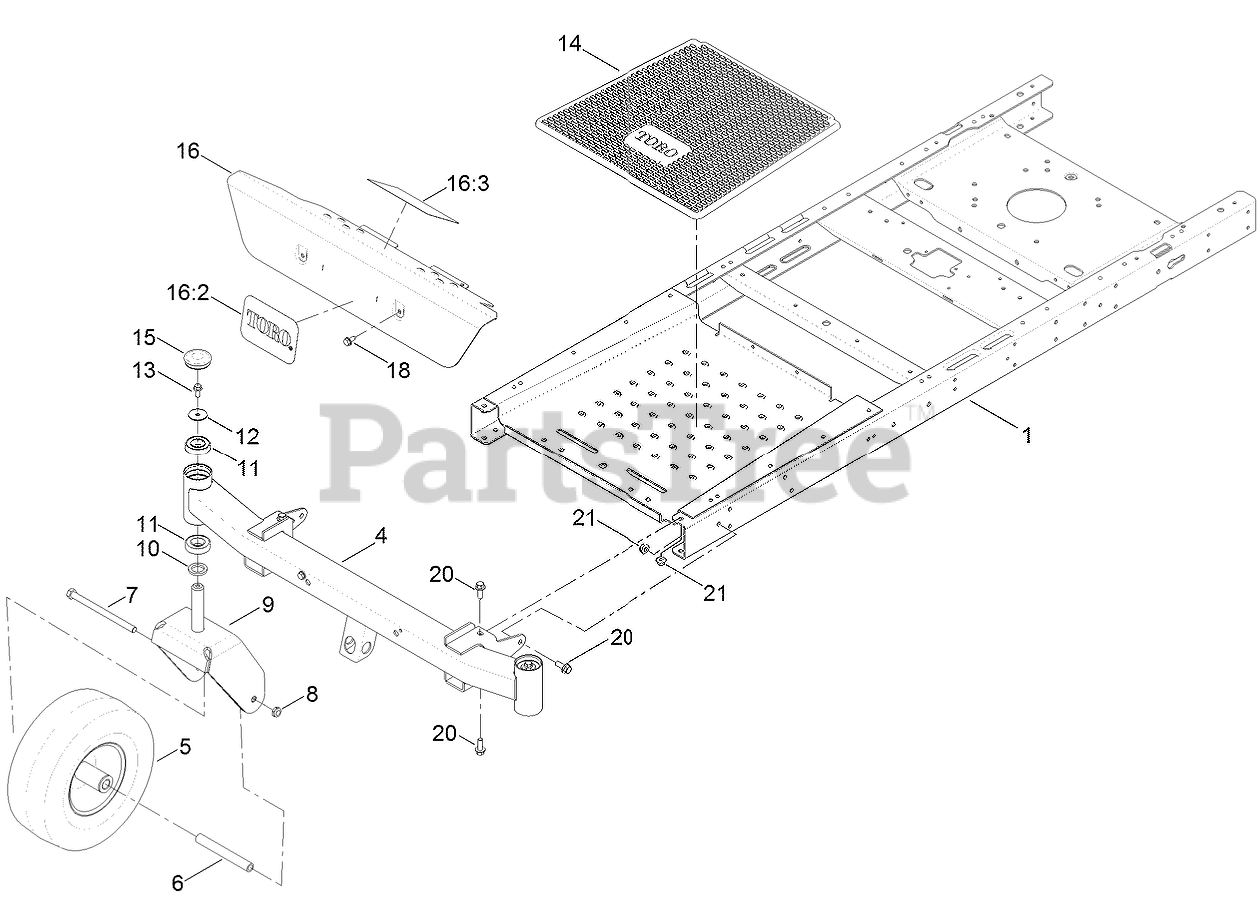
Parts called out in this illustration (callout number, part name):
1	FRAME ASM
4	AXLE ASM
5	13 INCH WHEEL AND TIRE ASM
6	SPANNER
7	SCREW-HH
8	NUT-LOCK, NI
9	FORK-CASTER
10	WASHER-THRUST
11	BEARING-BALL
12	WASHER-FLAT
13	SCREW-HHF
14	MAT-FLOOR
15	CAP-GREASE
16	Footrest ASM
16:2	DECAL
16:3	DECAL-DANGER
18	SCREW-HWHTF
20	SCREW-HHF
21	NUT-HF, NI
